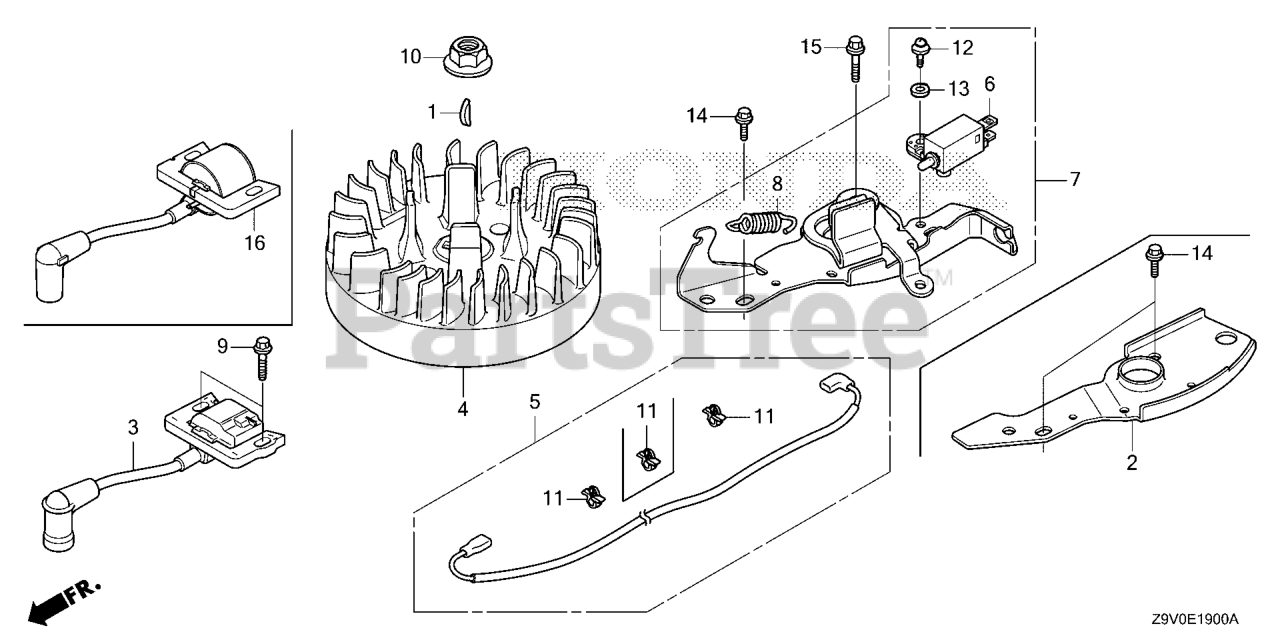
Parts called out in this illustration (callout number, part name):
1	KEY, SPECIAL WOODRUFF (25X18)
3	COIL ASSY., IGNITION
5	WIRE, STOP SWITCH
6	SWITCH ASSY., ENGINE STOP
7	BRAKE ASSY.
8	SPRING, BRAKE LEVER
9	BOLT, FLANGE (6X23)
10	NUT, FLANGE (14MM)
11	CLIP, HARNESS BAND (145MM) (BLACK)
12	SCREW-WASHER (4X12)
13	WASHER, PLAIN (4MM)
14	BOLT, FLANGE (6X14)
15	BOLT, FLANGE (6X22)
